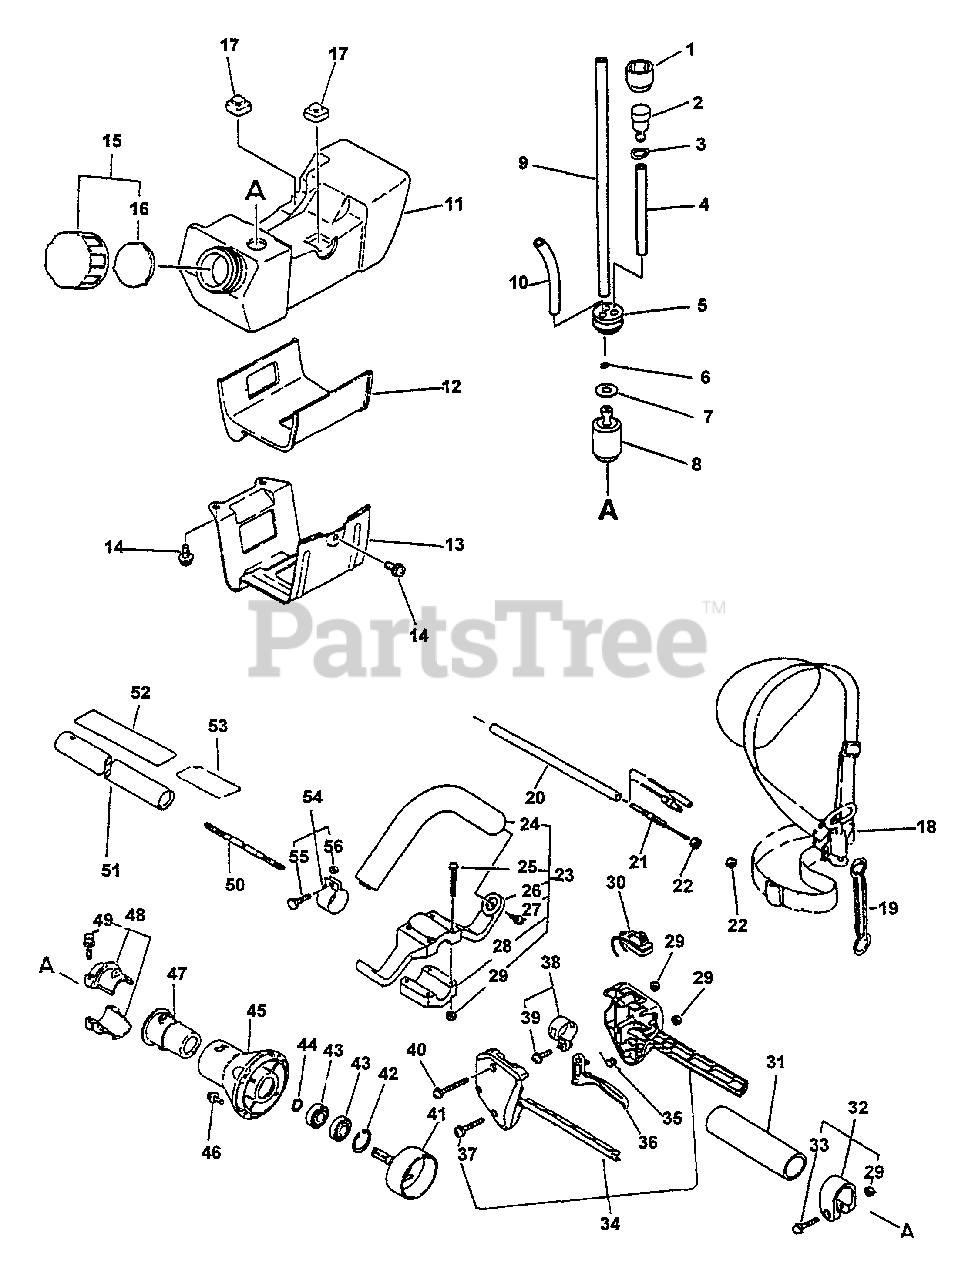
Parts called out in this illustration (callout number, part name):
1	HOLDER, VENT
2	VENT ASSY
3	CLIP 6 MM
4	PIPE, FUEL VENT 3×5×60
5	GROMMET, FUEL
7	WASHER 5.5×12×0.8
8	FILTER, FUEL
9	PIPE, FUEL 3x-5x-180
10	PIPE, FUEL RETURN 3×6×90 MM CLEAR
11	TANK, FUEL
12	CUSHION
13	GUARD, FUEL TANK
14	SCREW 5×10
15	CAP ASSY
16	GASKET, FUEL CAP
17	CUSHION
18	SHOULDER STRAP ASSY
19	HOOK
20	TUBE - VINYL
21	CABLE, THROTTLE
23	LOOP HANDLE ASSY
24	HANDLE
25	SCREW 5×35
26	BRACKET, HANDLE
27	SCREW 5×14
28	BRACKET, HANDLE - LOWER
29	NUT M5
30	SWITCH, ON-OFF
31	GRIP, HANDLE
32	CLAMP KIT
33	SCREW 5×28
34	HANDLE KIT, CONTROL
35	SPRING, TORSION
36	TRIGGER, THROTTLE
37	SCREW 5×25
38	CLAMP KIT
39	SCREW 5×14
40	SCREW 5×35
41	DRUM, CLUTCH
42	RING, SNAP 28
43	BEARING, BALL 6001
44	RING, RETAINING - 12
45	CASE, CLUTCH - GRAY
46	SCREW 5×16
48	HOLDER KIT
49	BOLT - 5×25
50	DRIVESHAFT
51	HOUSING ASSY
52	LABEL - CAUTION
53	LABEL - CAUTION
55	BOLT 5×18
56	SPACER, GUARD
